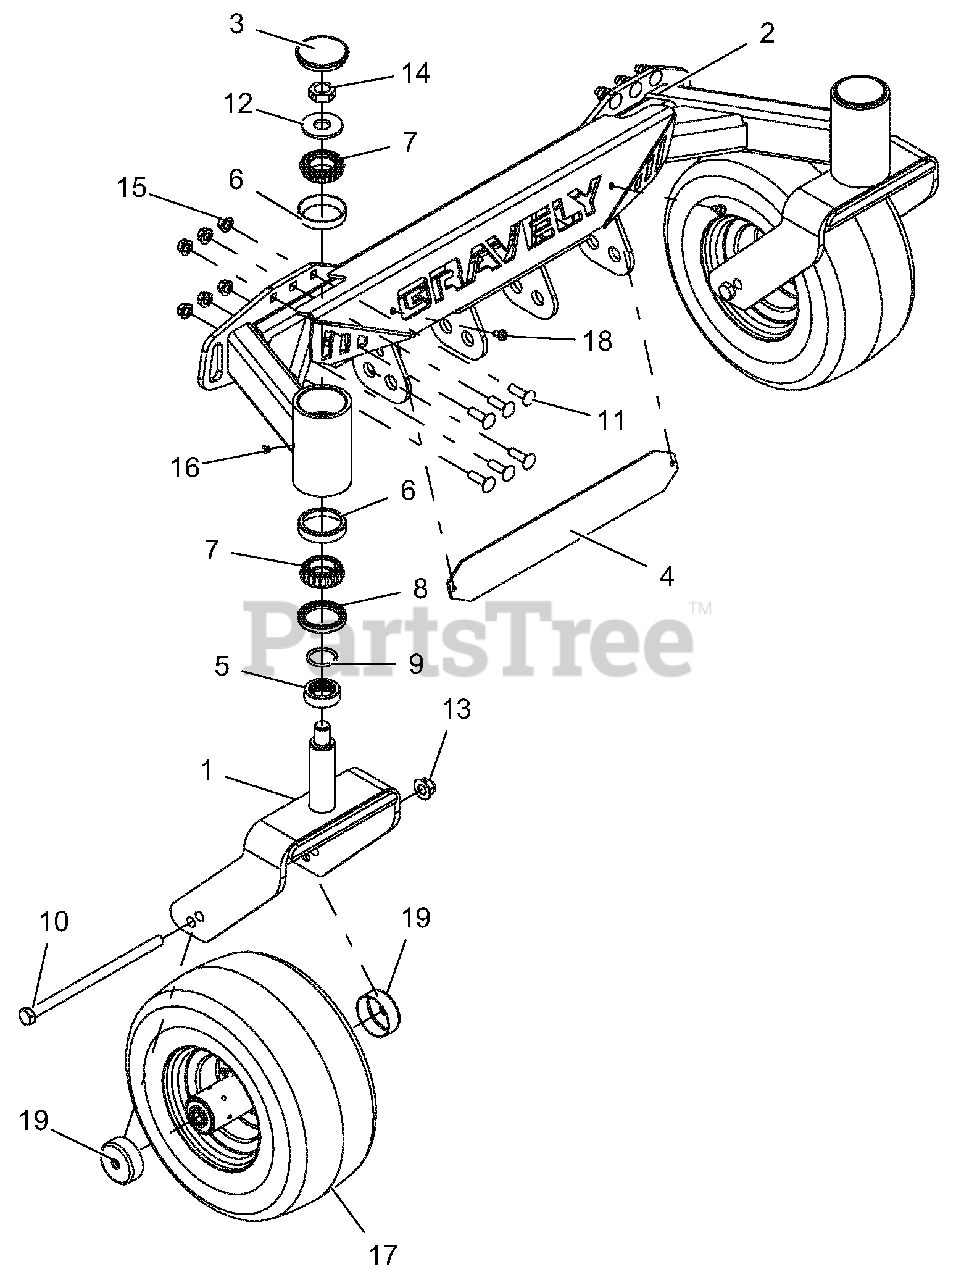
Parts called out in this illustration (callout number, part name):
1	WMT, CASTER FORK - RED
2	WLDMT, FRONT 60 AXLE
3	CAP, DUST
4	PLATE, BACK NAME-BLACK
5	SPCR, FRONT CASTER FORK
6	BRG, CUP 2.328 X .465
7	BRG, CONE 1.250 X .660
8	SEAL, OIL 1.75 X 2.332 X .312
9	O-RING, .139 W X 1.234 ID
10	BLT-HEX .50-13X9.00 GR5 YWZC
11	BLT-RDHDSQNK .38-16X1.25 G5 YWZC
12	WSHR-FL-STL.812X2.00X.148YWZC
13	NUT-LK-NYL-FLG .50-13 YWZC
14	@NUT-LK-CTR-JAM .75-16 YWZC
15	NUT, LK-TOP-FLG .38-16 YWZC
16	PLUG, .250-28 X .185 HEX HEAD
17	TIRE/WHEEL, 13 X 6.50-6 SEMI PNEU
18	SCR-TAP .25-20X.50 HWH TR YWZ
19	SHIELD, WHEEL BEARING
